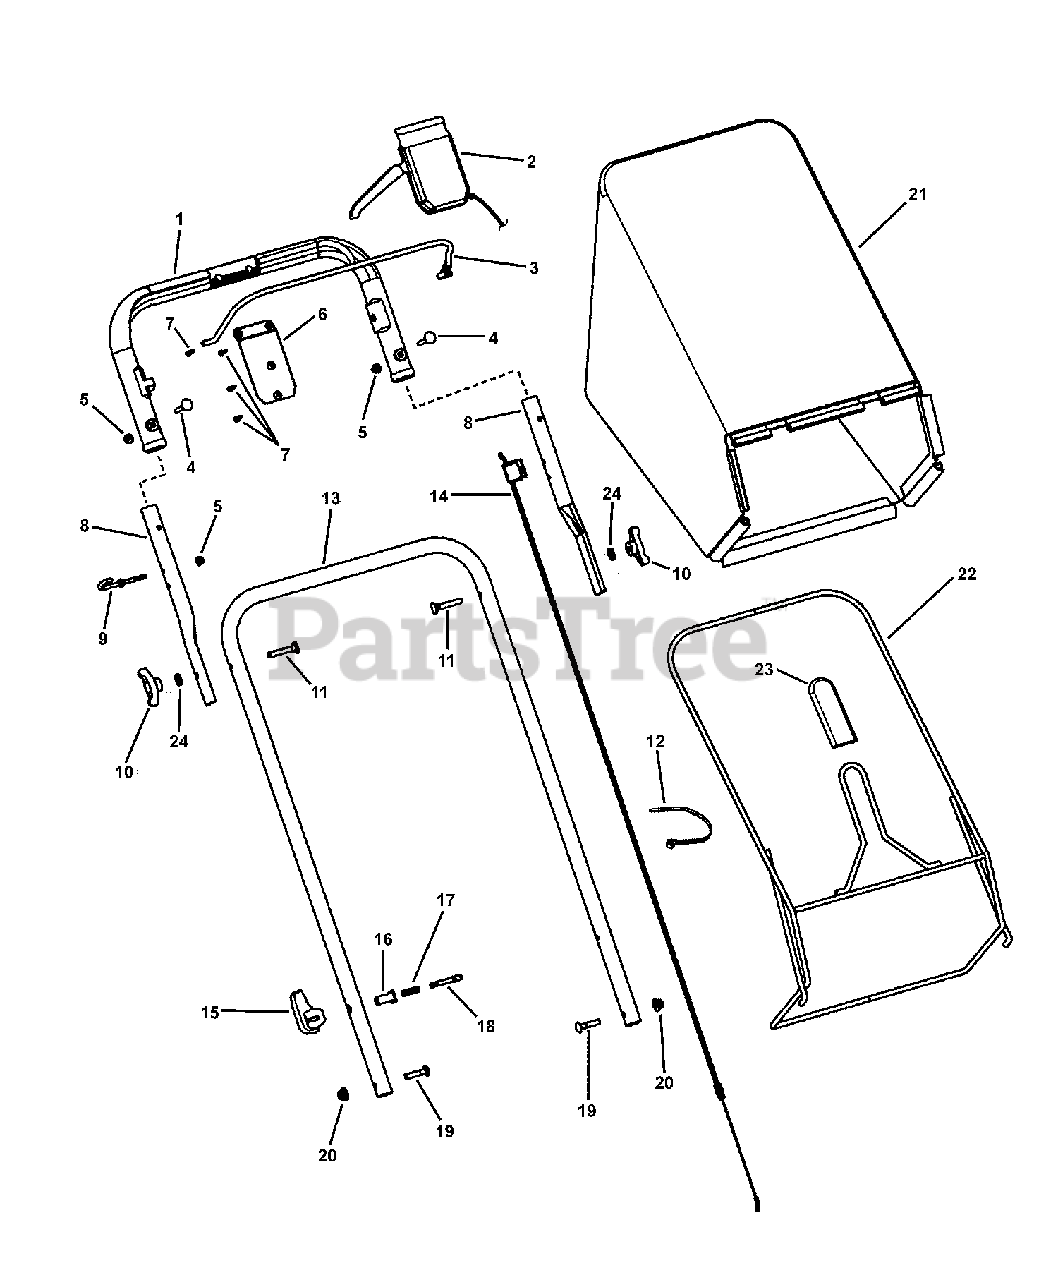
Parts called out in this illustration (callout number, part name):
1	HANDLE, Plastic Upper, WBM
2	ASSEMBLY, Control Head, 22" WBM, VS, HW (incl. cable & handle)
3	BAIL, Plastic Handle, WBM
4	BOLT, 1/4-20 x 1-3/4" Round Head Square Neck, GR 2
5	NUT, 1/4-20 Hex Flange Nyloc,YZ
6	PLATE, Control Panel- Plastic Handle
7	SCREW, Pan Head Cross Recess, Self-Tap
8	HANDLE, Connecting 21"/22" WBM
9	ROPE GUIDE, (1/4-20 thread)
10	KNOB, 5/16-18 Wing (Black)
11	BOLT, 5/16-18 x 2" Curved Head Square Neck, GR 2
12	WIRE TIE, 11 Inch Standard Black Nylon
13	HANDLE, Lower, 22" WBM, Hi-Wheel
14	CABLE, Bail, 22" WBM
15	KNOB, Quick Release
16	BUSHING, Handle Pin
17	SPRING, Compression
18	PIN, Handle Adjust
19	BOLT, 5/16-18X x 1-1/2" Round Head Short Square Neck, GR 5
20	NUT, 5/16-18 Large Head Center Lock, Black
21	GRASSBAG, 22" Rear Discharge
22	BAG FRAME, 22" WBM
23	GRIP, Rectangular (Black)
24	WASHER, 5/16" Internal Tooth Lock
